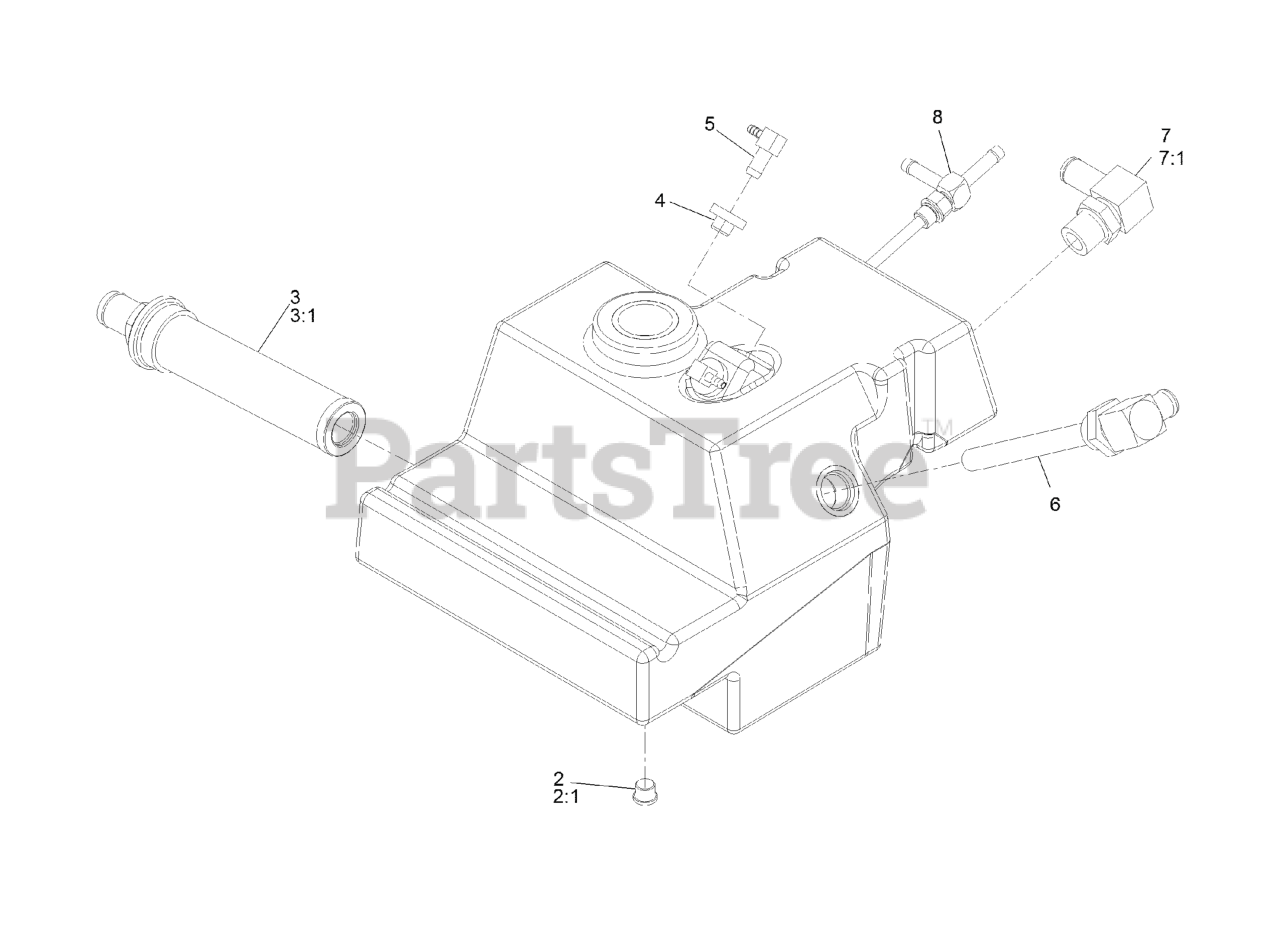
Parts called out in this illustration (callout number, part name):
2	PLUG-HEX, HOLLOW
2:1	O-RING
3	TANK STRAINER ASM
4	BUSHING
5	FITTING-ELBOW, 90 DEG
6	Fitting-Standpipe
7	FITTING-ELBOW, 90
7:1	O-RING
8	FITTING-TEE, DROP TUBE
